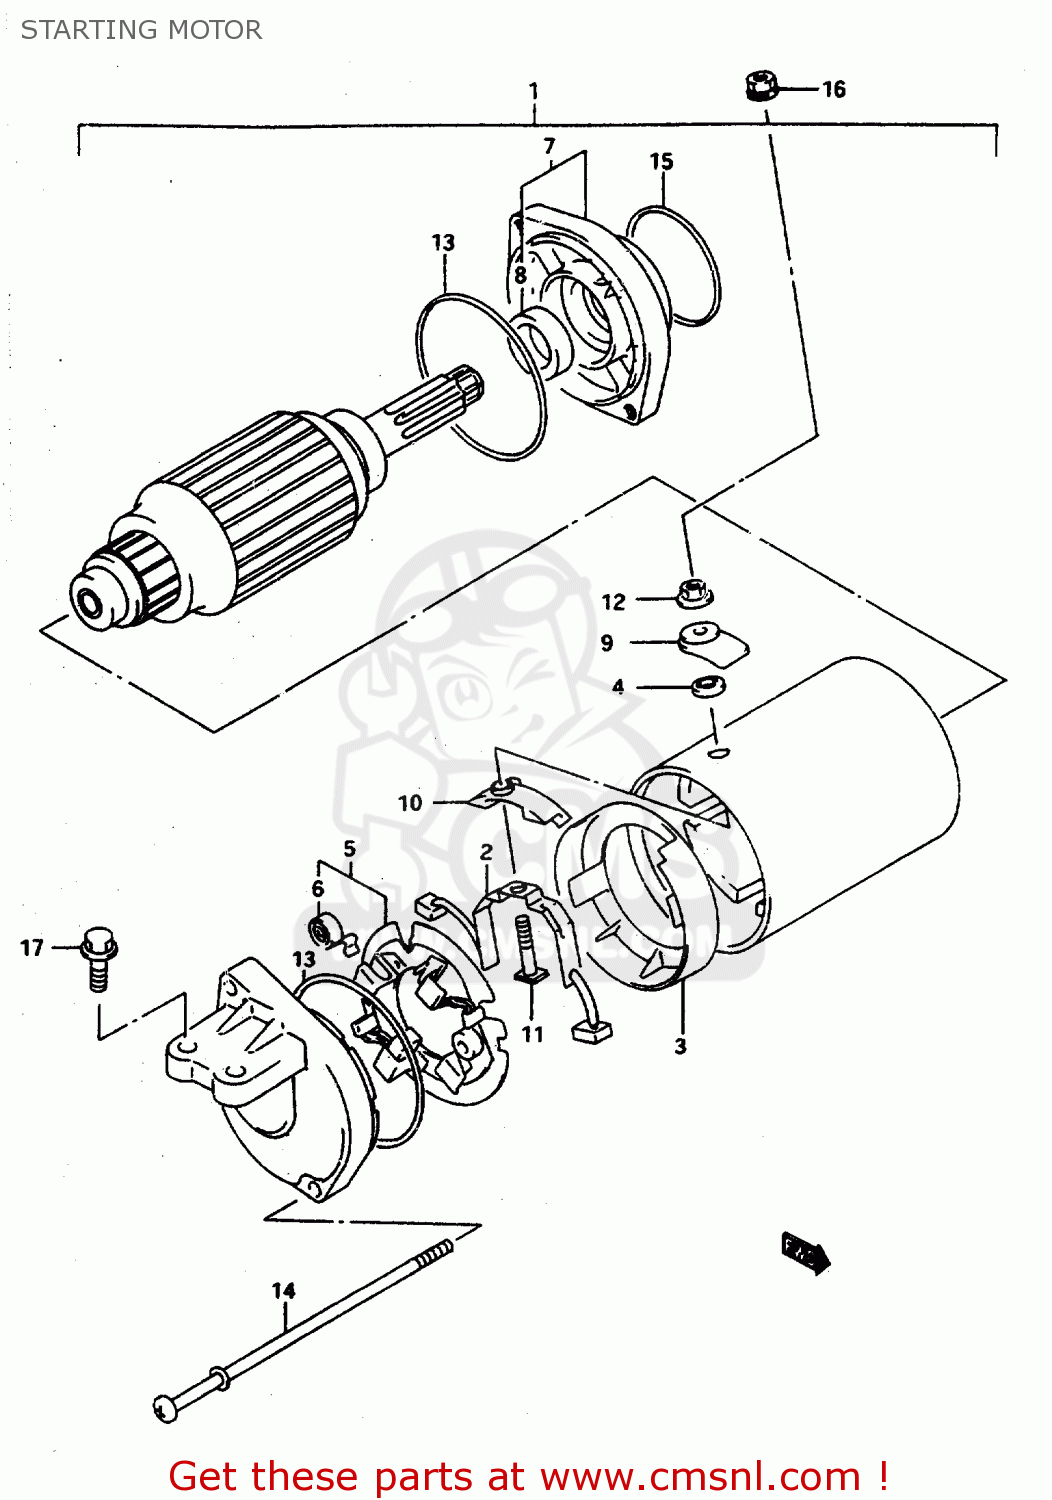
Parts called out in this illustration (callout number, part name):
1	MOTOR ASSY, STARTING
2	TERMINAL SET,BRUSH
3	INSULATOR
4	GASKET (NAS)
5	HOLDER SET,BRUSH(-)
6	SPRING
7	BRACKET SET
8	SEAL,OIL
9	BUSHING
10	BUSHING
11	BOLT
12	NUT
13	O RING
14	BOLT
15	O-RING (D:2.0)
16	NUT
17	SCREW
